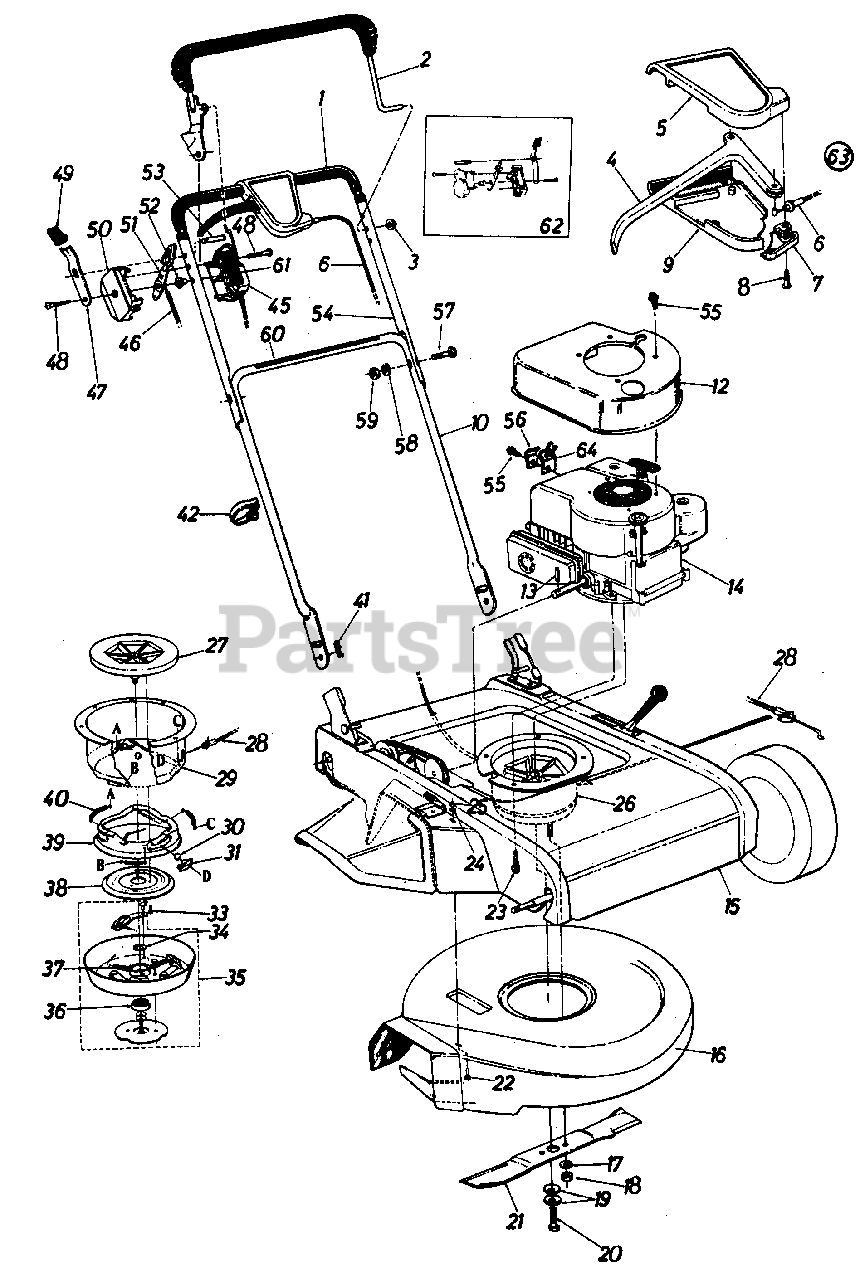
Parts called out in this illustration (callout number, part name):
2	Control Handle-R.H.
3	Cap Speed Nut 5/16 Rod
4	Control Lever
5	Control Cover Half-Upper
6	Drive Clutch Cable-59"
7	Cable Mounting Cap
8	Flat C'Sunk Hd. Tap Scr. #10x 1" Lg.
9	Control Cover Half-Lower
10	Lower Handle
13	Spring Pin 3/16 Dia. x 1.5" Lg.
14	Engine
15	Upper Deck Ass'y.
16	Lower Deck Ass'y.
17	L-Wash. 3/8" I.D.*
18	Hex Nut 3/8-24 Thd. (Grade 8)
19	Belleville Washer
20	Hex Bolt 3/8-24 x 2" Lg. (Grade 8)
21	21" Blade
22	Carr. Bolt 5/16-18 x .62" Lg.
23	Hex Wash. Hd. TT-Tap Scr. 3/8-16x1" Lg.
24	L-Wash. 5/16" I.D.*
25	Hex Nut 5/16-18 Thd.*
26	Blade Brake/Clutch Ass'y. Comp.
27	Fan Adapter
28	Blade Clutch Cable-46"
29	Clutch Housing
30	Steel Ball 1/2" Dia.
31	Ball Block
33	Hex TT-Tap L-Scr. 1/4-20 x .75" Lg.
34	Fl-Wash. .69" I.D. x 1.06" O.D.
35	Clutch Blade Housing Ass'y.
36	Ball Bearing
37	Compression Spring
38	Clutching Cone
39	Brake Cup Cone
40	Extension Spring
41	Int. Cotter Pin 5/16" Dia.
42	Cable Tie
45	Clutch Panel Half
46	Throttle Wire-43"
47	Lockout Spring
48	Truss Mach. Tap Scr. #12 x 1.5" Lg.
49	Spring Lever Knob
50	Control Panel Half
51	Throttle Control Lever
52	Control Disc Pin
54	Upper Handle
55	Hex AB-Tap Scr. #8 x .38" Lg.
56	Casing Clamp
57	Curved Carriage Bolt 5/16-18 x 1.38" Lg.
58	L-Wash. 5/16" I.D.*
59	Hex Nut 5/16-18 Thd.*
60	Instruction Label-Handle
61	Control Label-Throttle
62	Control Housing Comp.
63	Clutch Control Housing Comp.
64	Casing Clamp
